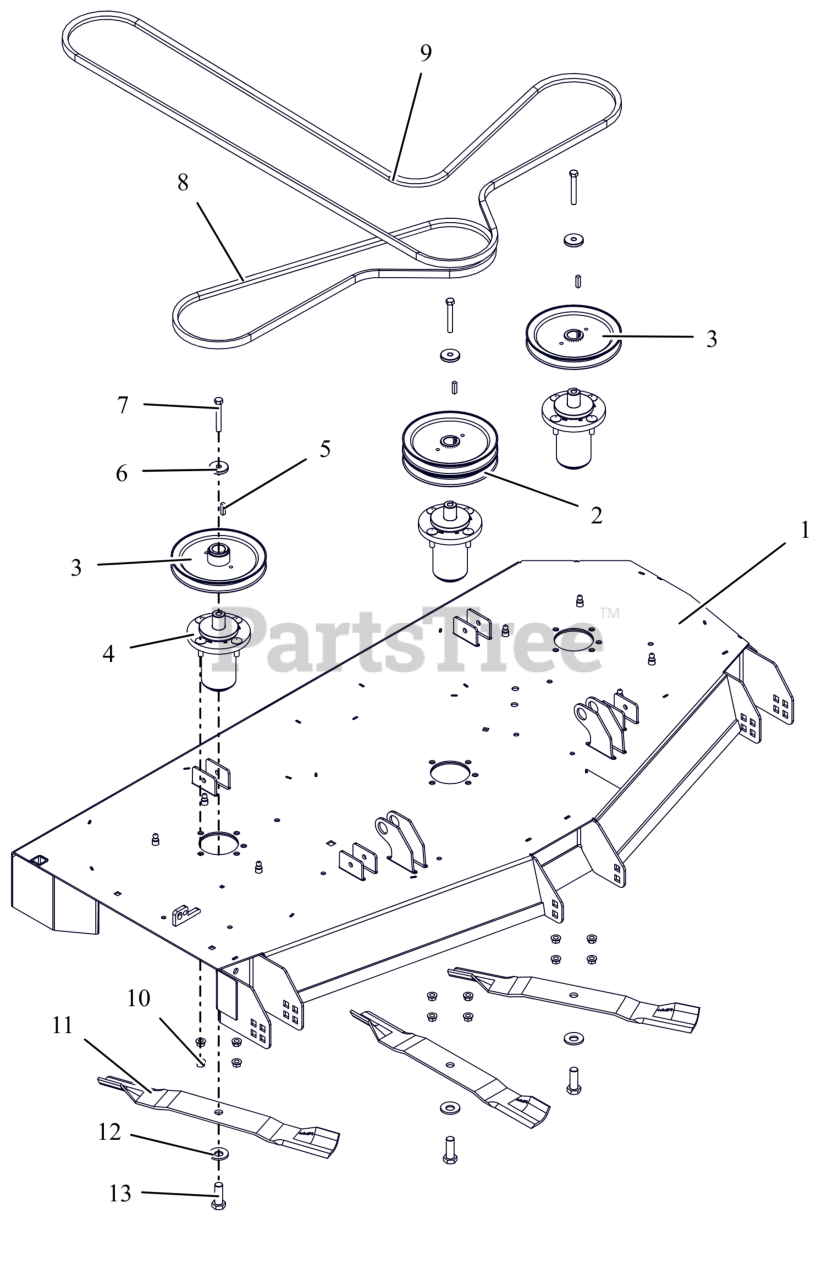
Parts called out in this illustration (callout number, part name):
1	KIT,DECK-60 W/ DECALS -XF3 (BLACK)
1	KIT,DECK-60" W/DECALS -XF3 BLK
2	PULLEY, DOUBLE-1"X7.50"&7.50"
3	PULLEY, V-7.50 OD X 1" ID
4	ASM, MAINT FREE ALUM SPINDLE
5	KEY, SQ .25X.25X1.00 RC 40-50
6	RETAINER, SHEAVE
7	BLT, HEX .38-16X2.75 G8 ZCC
8	V-BELT, B-COGGED
9	V-BELT, HB SECTION
10	NUT-LK-CTR-FLG .375-16 GF ZCC
11	BLADE, 20.5"
12	WSHR-BLVL .669X1.535X.138
13	BLT, HEX .62-18X1.75 G8 ZCC
